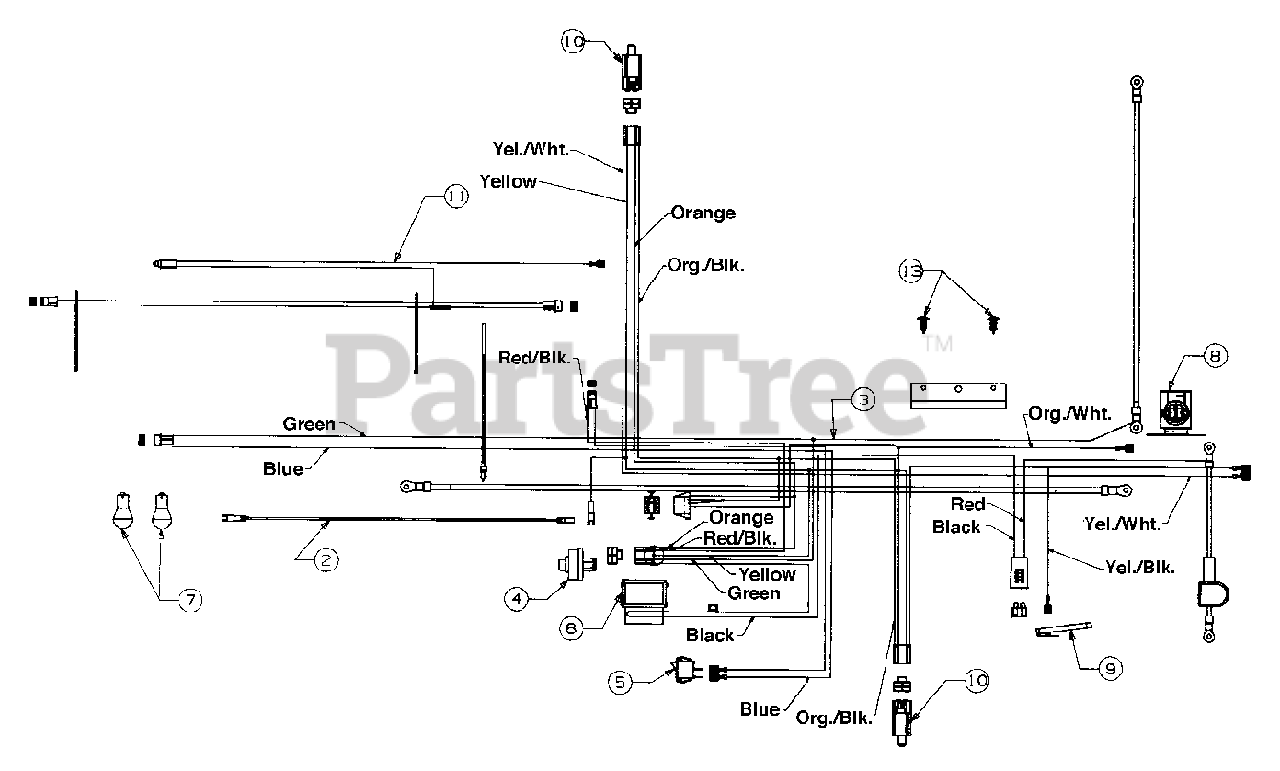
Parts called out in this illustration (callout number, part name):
2	Harness Adapter
3	Wire Harness w/Lt./Amp./Sw.
3	Wire Harness w/o Lt./Amp./Sw.
4	Ignition Switch - 5 Pin
4	Ignition Switch - 6 Pin
5	Light Switch
6	Ammeter
7	Bulb
8	Solenoid
9	Safety Switch (Reverse)
10	Safety Switch
11	Harness Adapter (Alt.)
